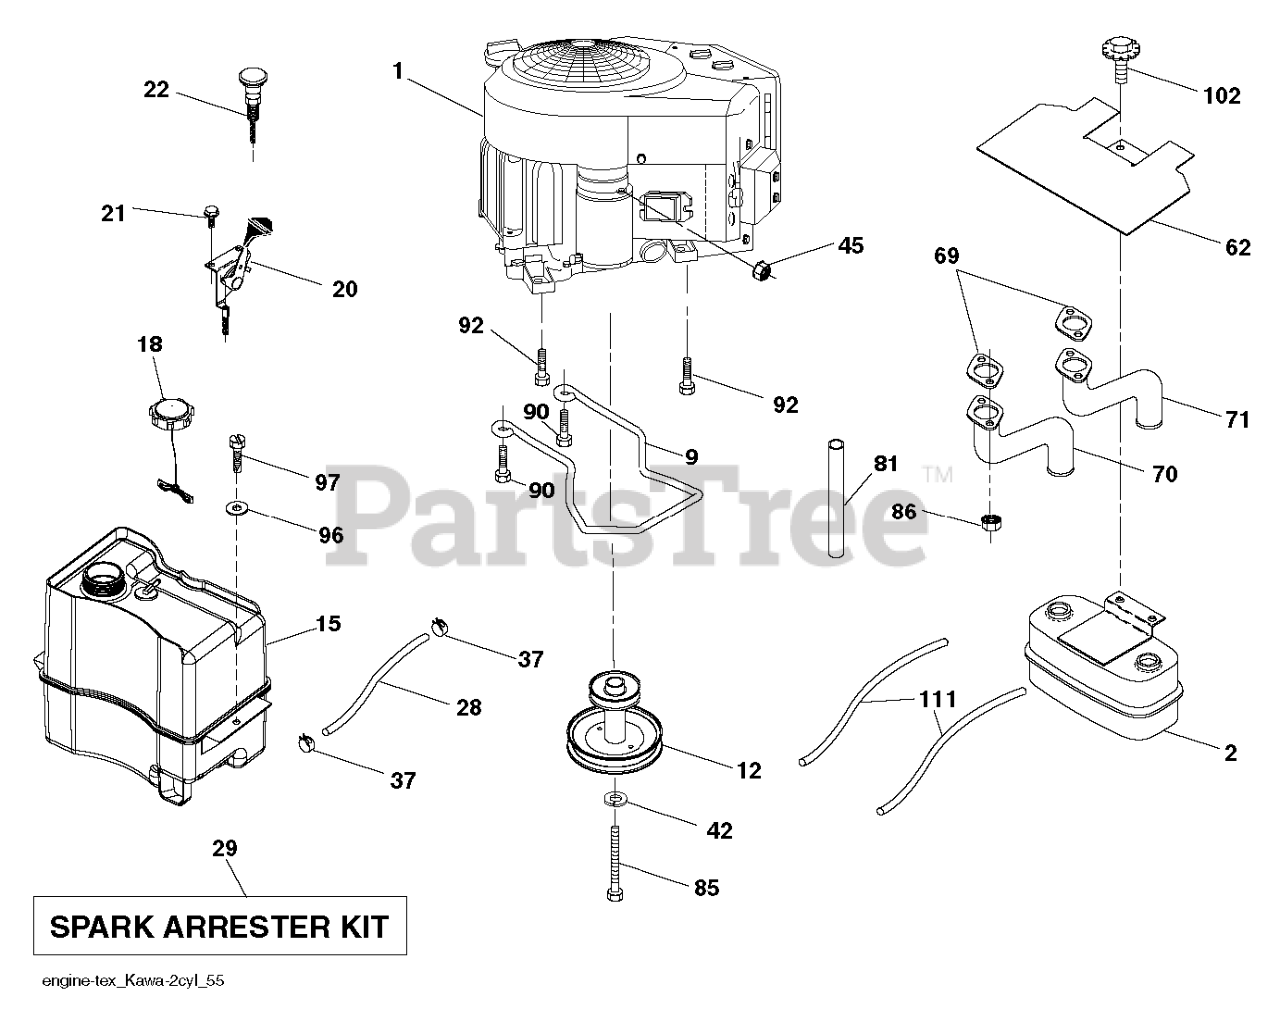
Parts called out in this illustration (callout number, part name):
2	MUFFLER.ASM.TWIN.MNTG.BRACKET
9	KEEPER.BELT.ENG.4.25"2.BLT.431
12	PULLEY.ENGINE
15	TANK.ASM.FT.2.5GAL.W/CAP.EPA17
18	CAP.2.25'.VENTED.TETHER .EPA
20	CONTROL.THROTTLE.COBRA.BLACK
21	SCREW.#10 X 0.750.BOS
22	CONTROL, CHOKE
28	HOSE 1/4" LOW PERMEATION FUEL
29	KIT.SPARK ARRESTOR 794945 B&S
37	HOSE CLAMP
42	WASHER 7/16 LOCK
45	NUT
62	SHIELD.HEAT.MUFFLER
69	GASKET.EXHAUST.KOHLER
70	TUBE.EXHAUST.RH.FR961/FR730
71	TUBE.EXHAUST.LH.FR961/FR730
81	TUBE, DRAIN OIL ASM.
85	BOLT.HEX.7/16-20X4.GR5.1.5BLUE
86	BLADE ADAPTER
90	SCREW 3/8-16X1
92	SCREW 3/8-16X1
97	SCREW HEXWSHR 1/4-20X3/4
102	SCREW
111	RP PURGE LINE
